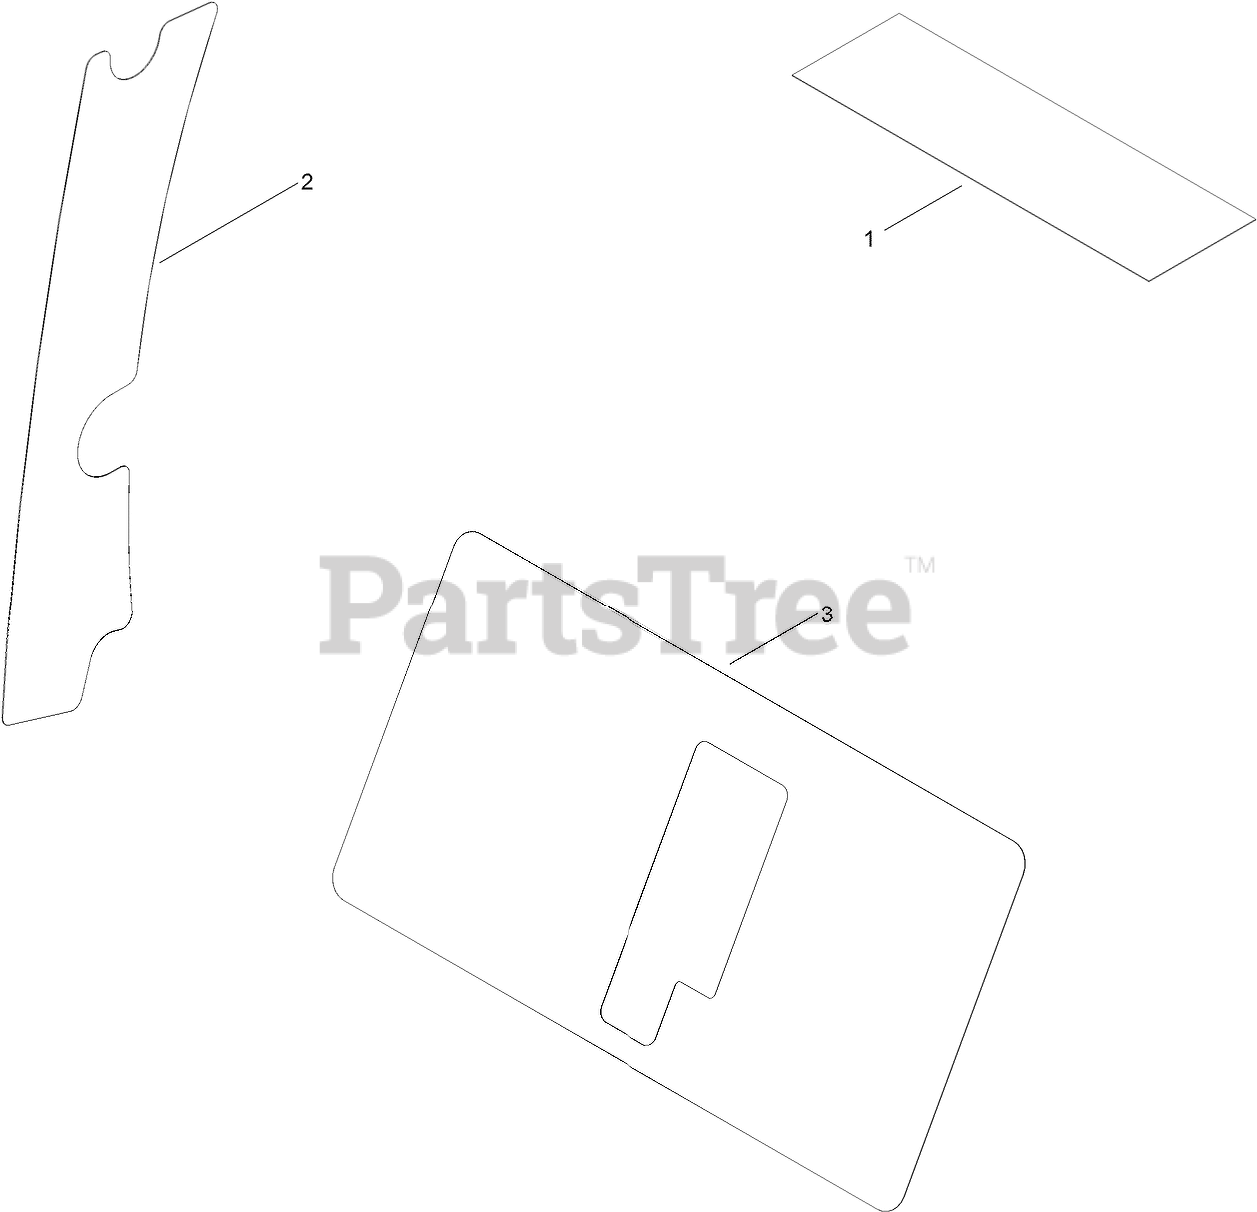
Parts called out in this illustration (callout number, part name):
1	DECAL-SERVICE, CE
2	DECAL-HOC
3	DECAL-CONTROL, SPEED
